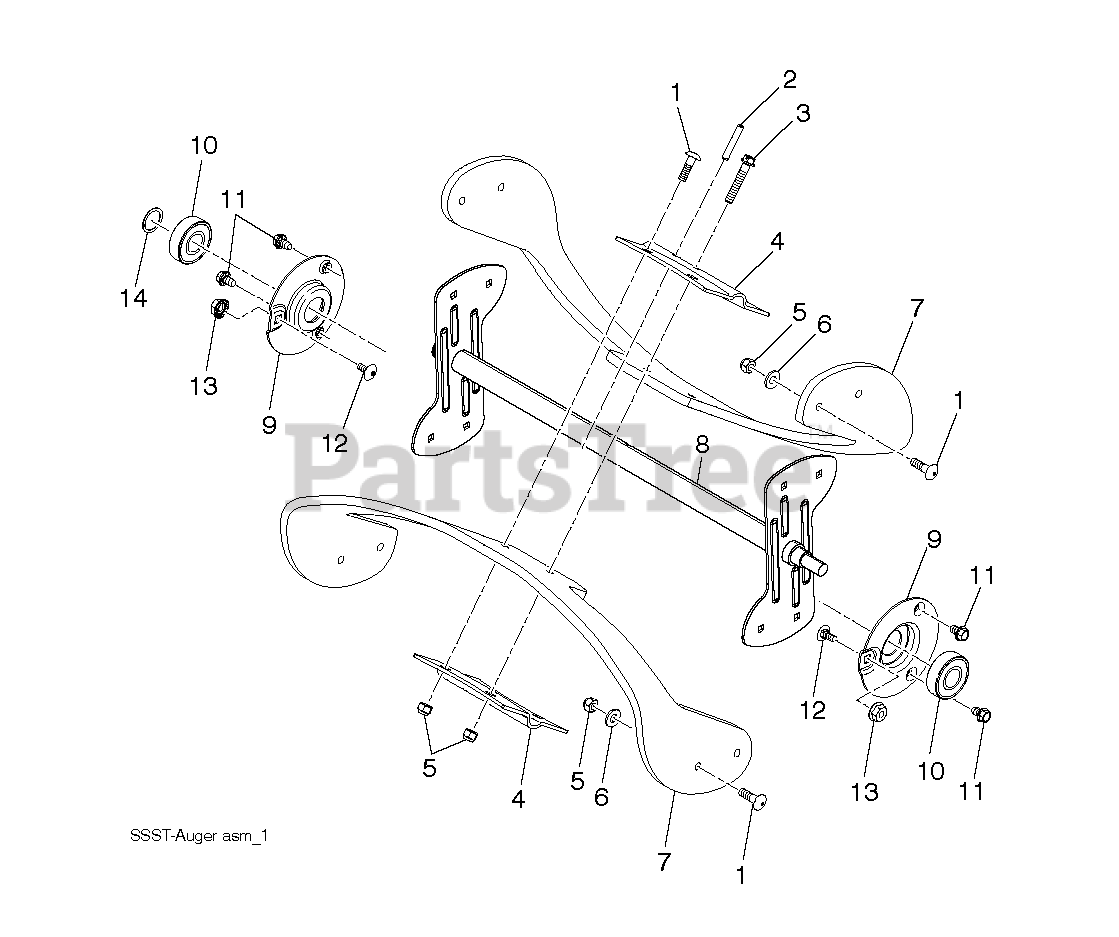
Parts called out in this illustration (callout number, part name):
1	BOLT.CARRIAGE.1/4-20 X 7/8
2	PIN.ROLL.3/16 X 1-1/4
4	PLATE.CENTER.BLADE
5	NUT
7	AUGER.BLADE.SS.SNOW
8	WELDMENT.AUGER.SINGLE.STAGE.BL
9	SUPPORT.BEARING.SSST.
10	BEARING.BALL.MANDREL
11	SCREW 1/4X20
13	NUT.FLANGE.1-4-20-SERR
14	RETAINING RING LT
